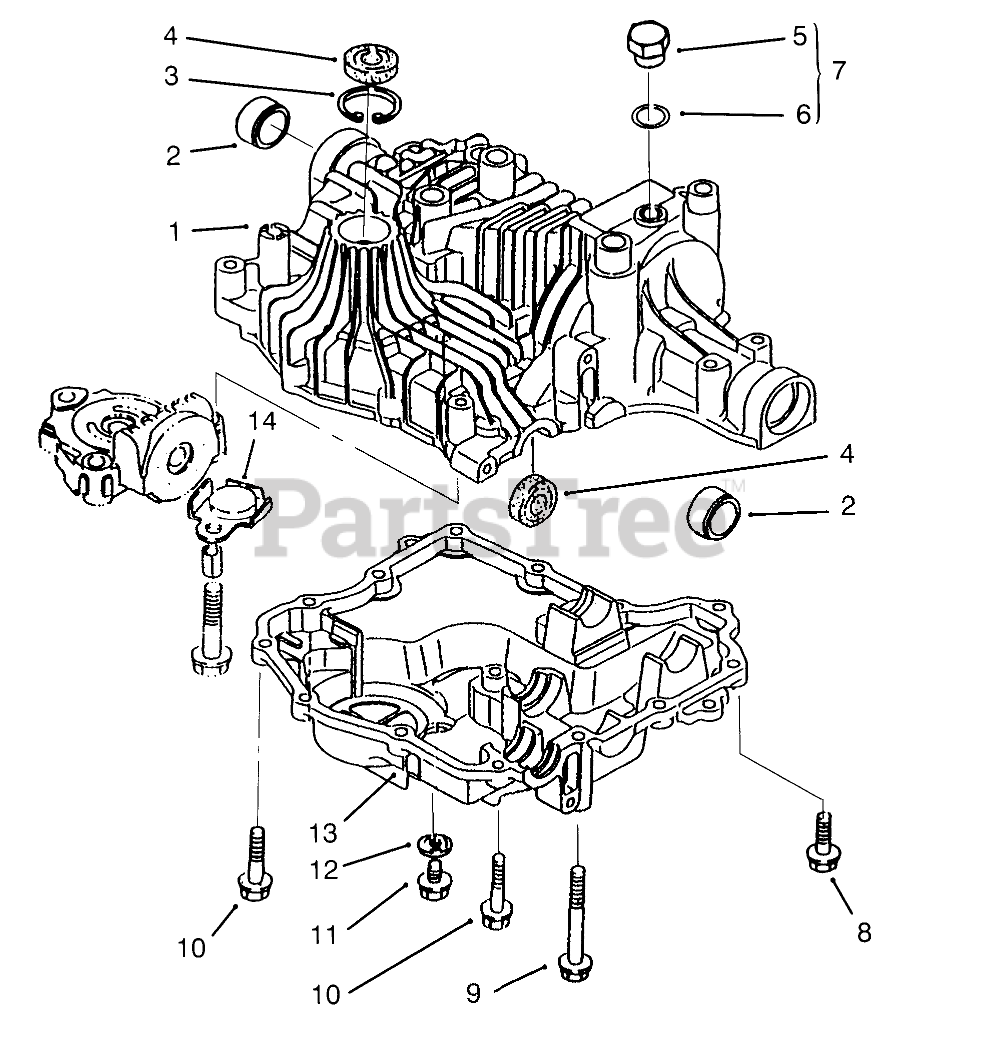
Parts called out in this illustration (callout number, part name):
1	Upper Case ASM INCL 2-6 (Only On: 72043,72063,72103)
3	Ring (Only On: 72043,72063,72103)
4	Seal (Only On: 72043,72063,72103)
7	Plug/Packing INCL 5-6 (Only On: 72043,72063,72103)
8	Screw-TAP (Only On: 72043,72063,72103)
9	Bolt (Only On: 72043,72063,72103)
10	Screw-TAP (Only On: 72043,72063,72103)
11	Bolt (Only On: 72043,72063,72103)
13	Case-Lower (Only On: 72043,72063,72103)
14	Magnet (Only On: 72043,72063,72103)
